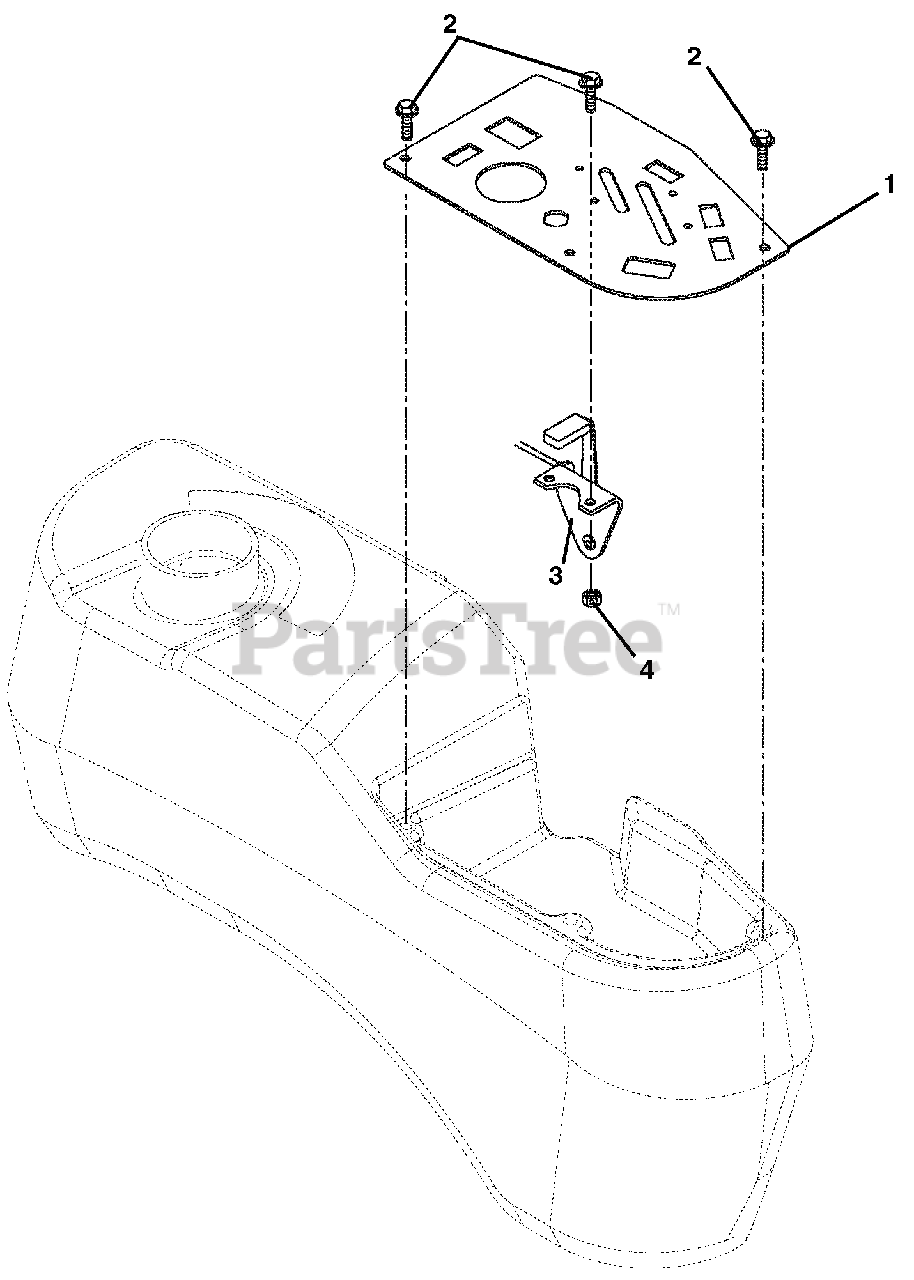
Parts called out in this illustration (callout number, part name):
1	Panel-Control
2	Screw-Machine 10-24 x .50 Hex Washer Head
3	Throttle, Control
4	Nut-Locking-Nylon 10-24 With Insert
